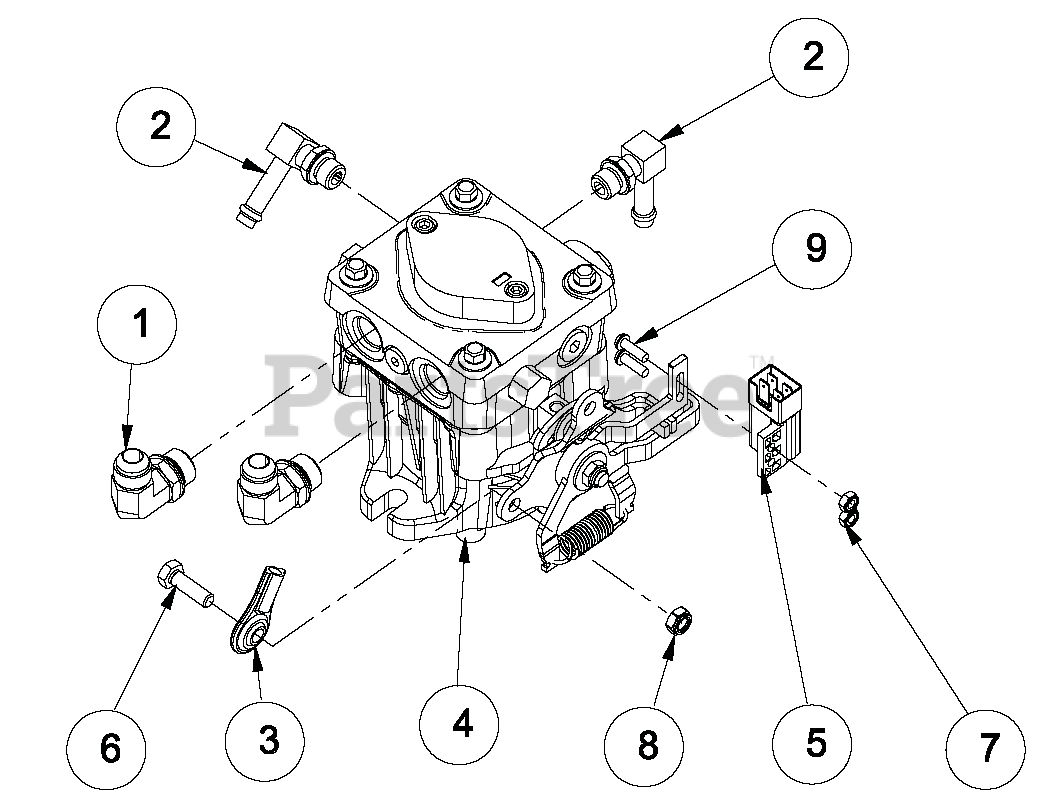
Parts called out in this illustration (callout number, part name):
1	FTG, 90 ADP JIC-ORB 6801-08-08
2	FTG, 90 9/16MOR X 3/8HOSE
3	ALIGNABALL, 5/16 RH/THREAD
4	PUMP, HYD RH
5	SWITCH, PLUNGER DP - N.O.-N.C.
6	BOLT, 5/16-18X1.00 HEX 5 Y
7	LOCKNUT, 10-24 NYLOC Y
8	LOCKNUT, 5/16-18 NYLOC Y
9	SCREW, 10-24X.625 PAN PHL MACY
